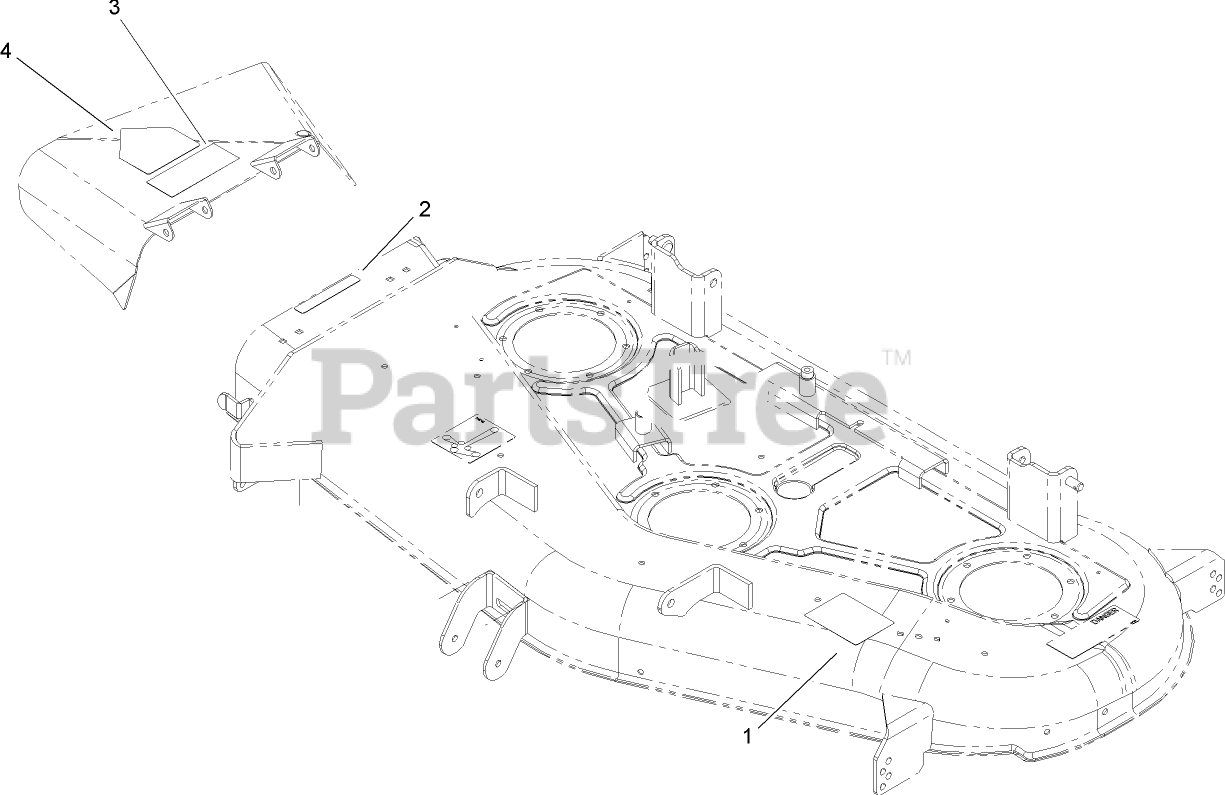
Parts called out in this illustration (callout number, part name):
1	DECAL-ANTI SCALP
2	DECAL-DANGER
3	DECAL-DANGER
4	DECAL-DANGER
